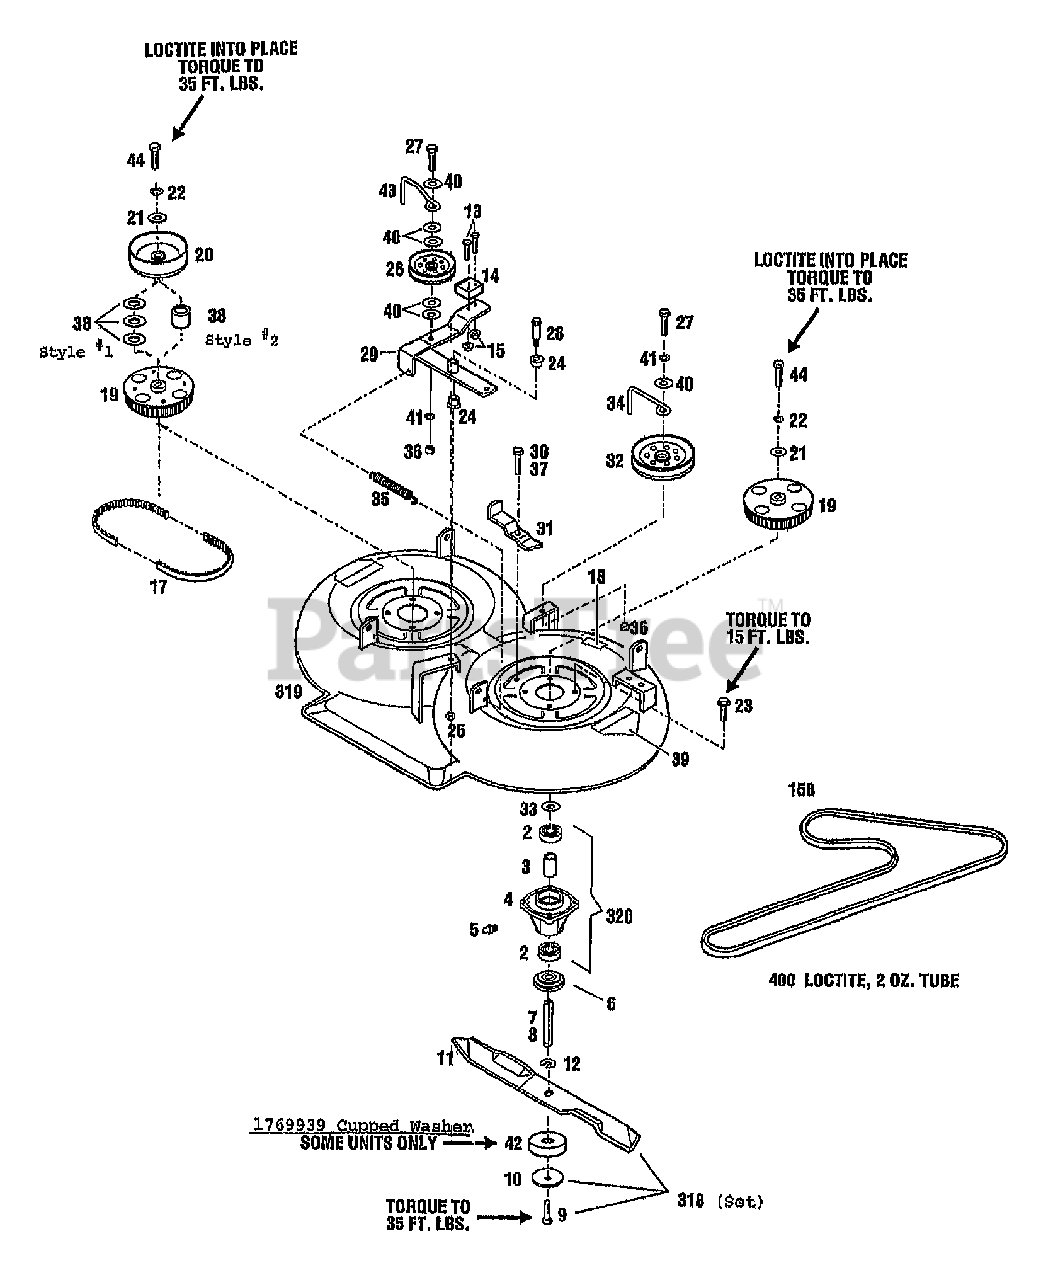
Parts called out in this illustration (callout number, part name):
2	BEARING-BALL
4	HOUSING-SPINDLE
5	FITTING-GREASE 1/4-28X2.00
6	SPACER-BLADE
7	SHAFT-SPINDLE MED. H/T
8	SPINDLE-SHAFT LONG H/T
9	SCR-HH 1/2-14X1.00
10	WASHER-BELLEVILLE
11	BLADE-33" MULCHING
12	RING-RETAINING EXT .694 ID
13	SCR-HW M10-24X1.25
14	PAD-BRAKE
15	NUT W/LKWASHER 10-24 ZP
17	BELT-DRIVE
18	DECAL-CAUTION PINCH POINT
19	COGGED PULLEY, 56T (SUPERCEDES 1765406)
20	PULLEY-BLADE DRIVE ZP
21	WASHER-1.37X.453X.179 ZP
22	WASHER-LK .438 ZP
23	SCR-HFLK 5/16-18X.75
24	BUSHING-.5X.5 NYLON FLNG
25	NUT-HFLK 3/8-16 ZP
26	PULLEY-IDLER
27	SCR-HH 3/8-16X2.50
28	SCR-SHLDR 3/8-16
29	ASSM-BRAKE ARM
30	SCR-HHC 5/16-18X.75 GR 5 ZP
31	BRKT-BELT TENSION ADJ
33	WASHER-THRUST .75 ID
34	GUIDE-BELT
35	SPRING-EXTENSION
36	NUT-HEX 3/8-16 ZP
37	NUT-TOP/LK 5/16-18 ZP
38	SPACER-PULLEY ZP
39	DECAL-OPEI CAUTION
40	WASHER-FLAT 3/8 SAE
41	WASHER-LK .375 @ DEPL
42	WASHER-CUP 2.76X1.0X.4 (SOME UNITS)
43	GUIDE-BELT
44	SCR-HH 7/16-14X1.25
158	BELT-V
318	KIT-2 BLADE WC MWR 33" (SUPERCEDES 1768492) SET OF 2 (INCL. 9,10 AND 318)
319	ASSM-DECK 33" (INCL. 39 & 18)
320	ASSM-MOWER SPINDLE (INCL. 2 - 5)
400	LOCTITE-242 (.5 ML TUBE)
